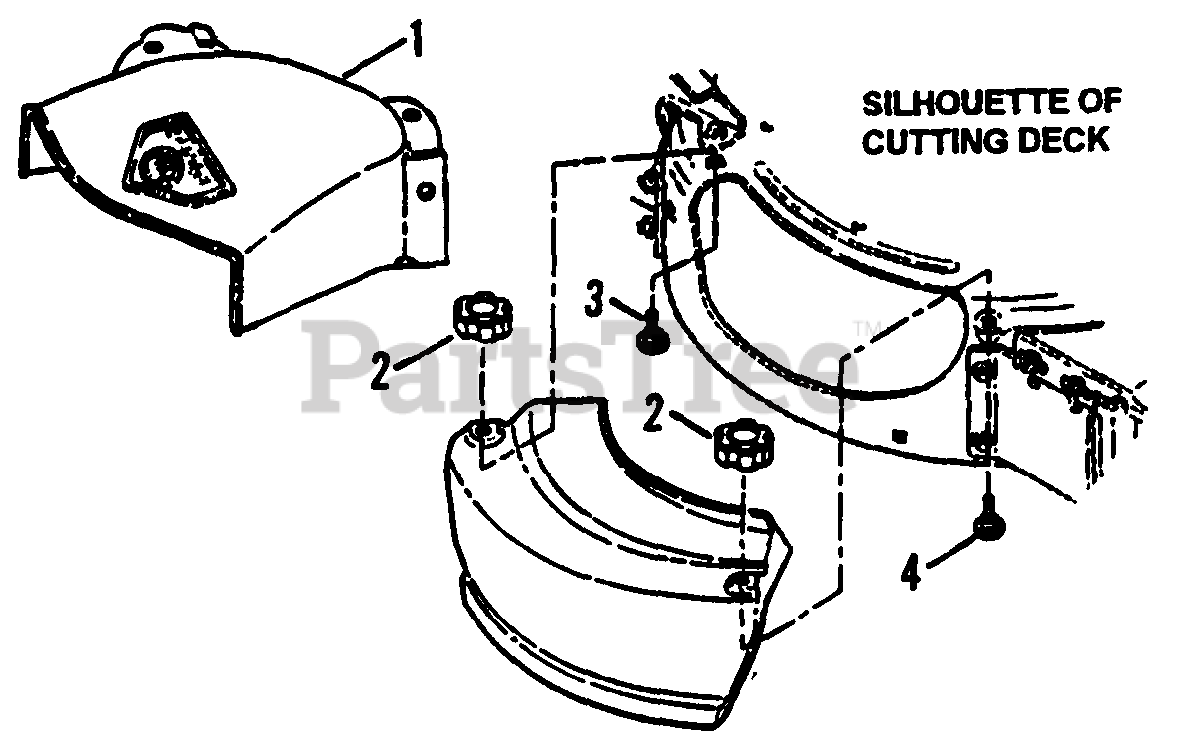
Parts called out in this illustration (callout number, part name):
1	CHUTE, Side 20
2	KNOB, Fluted, 5/16-18 Thread
3	BOLT, 5/16-18 x 3/4" Short Neck Carriage, Grade 5
4	COVER, Recycling (R204513E)
